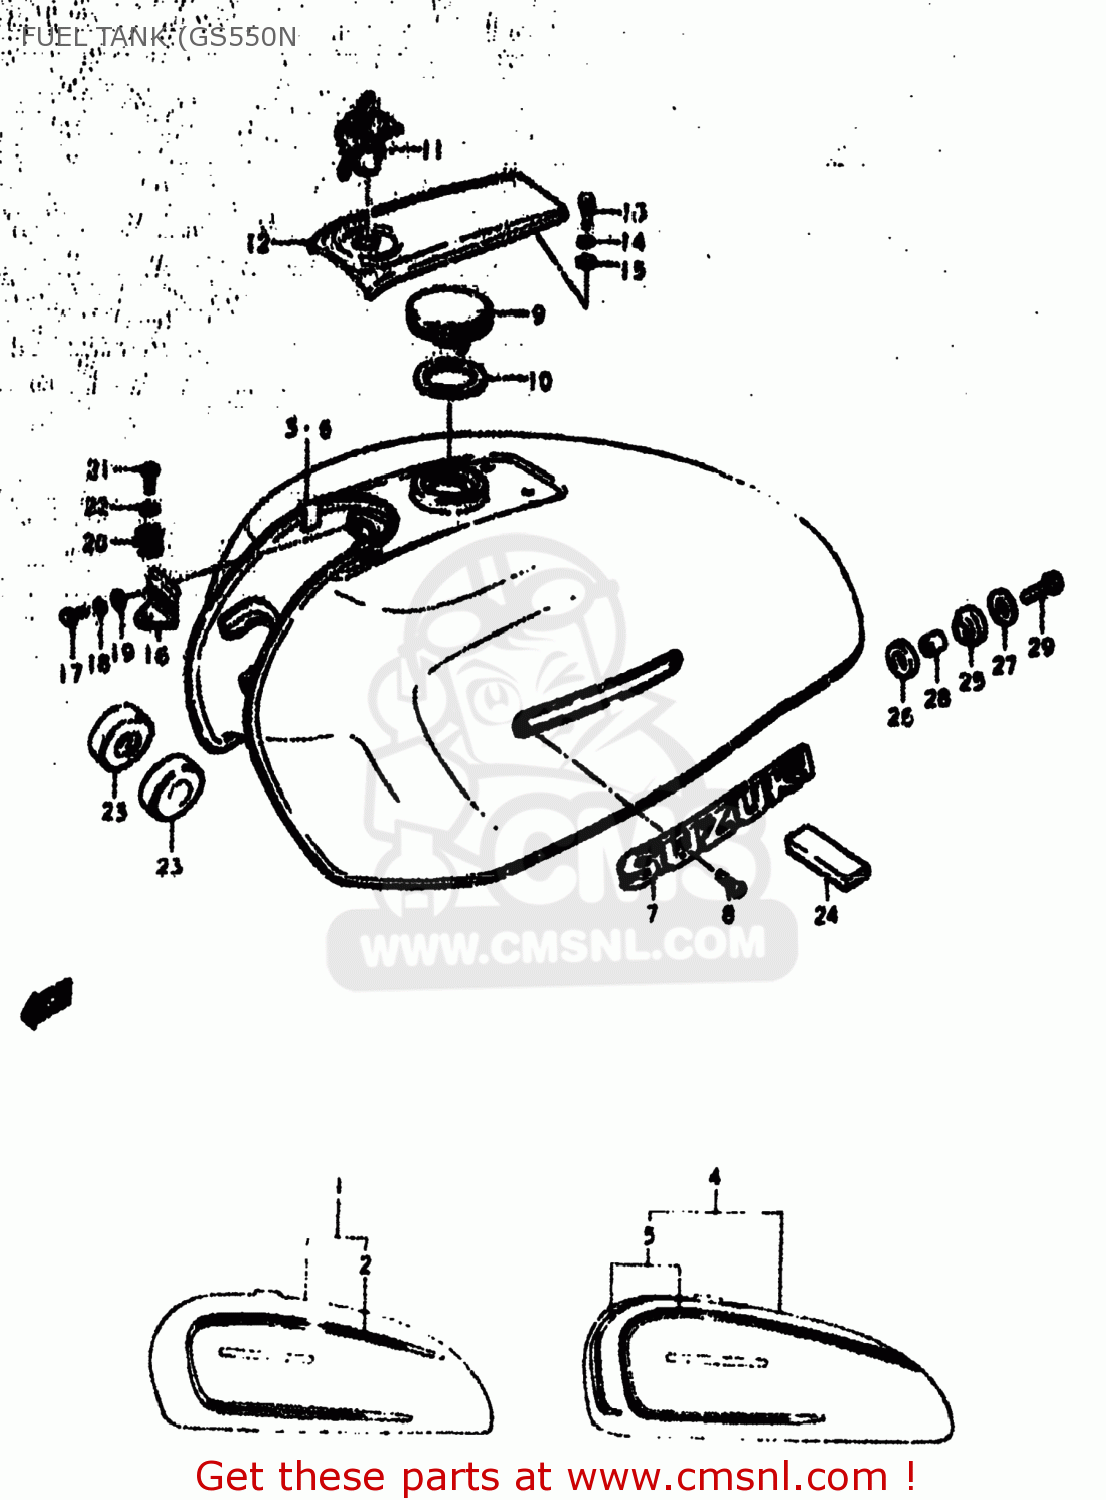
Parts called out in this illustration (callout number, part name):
1	TANK ASSEMBLY,FUEL
3	CUSHION,FUEL TANK FR COVER
4	TANK ASSEMBLY,FUEL
6	CUSHION,FUEL TANK FR COVER
7	EMBLEM,FUEL TANK
8	SCREW 3X6
9	CAP,FUEL TANK
10	GASKET (NAS)
11	LOCK,FUEL TANK FR COVER
12	COVER,FUEL TANK,FRONT
13	BOLT
14	LOCK WASHER
15	WASHER
16	HOLDER,FUEL TANK FRONT COVER
17	BOLT
18	LOCK WASHER
19	WASHER
20	SPRING
21	SCREW
22	LOCK WASHER
23	CUSHION
24	CUSHION
25	CUSHION
26	CUSHION
27	WASHER (8.7X22X2)
28	SPACER(8.5X12X19)
29	BOLT (8X30)
